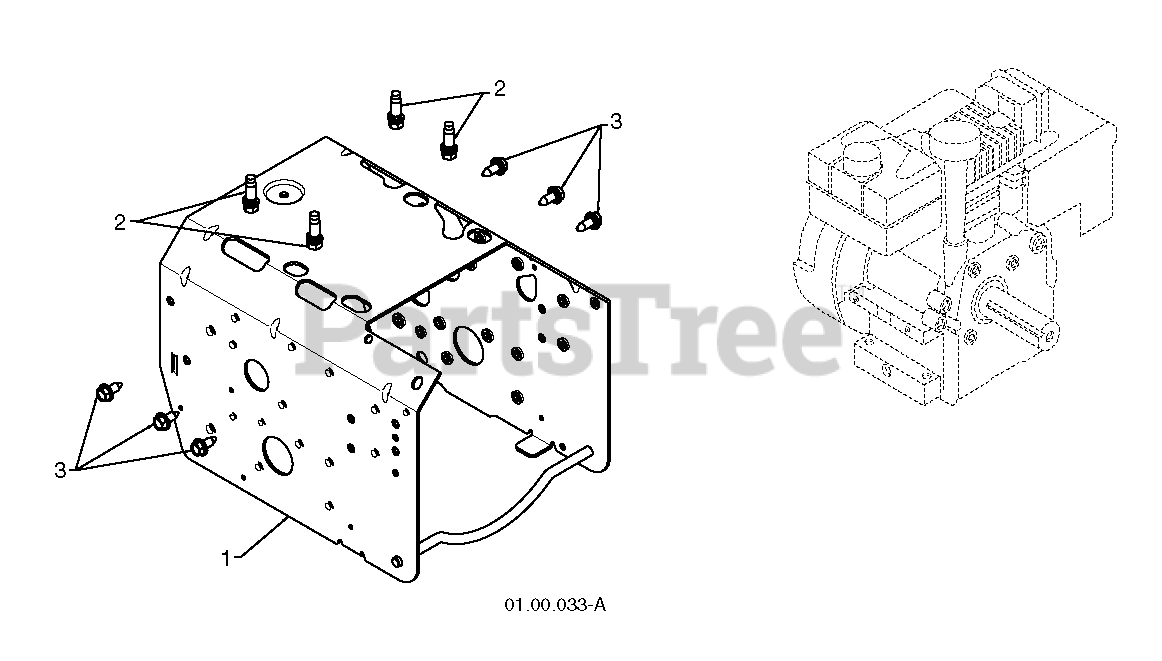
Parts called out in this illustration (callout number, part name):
1	FRAME.WELD.PNT.GEAR.ORANGE
2	BOLT 3/8-16X1-1/8
3	BOLT.HEX.HD.WASHER.5/16-18X.75
